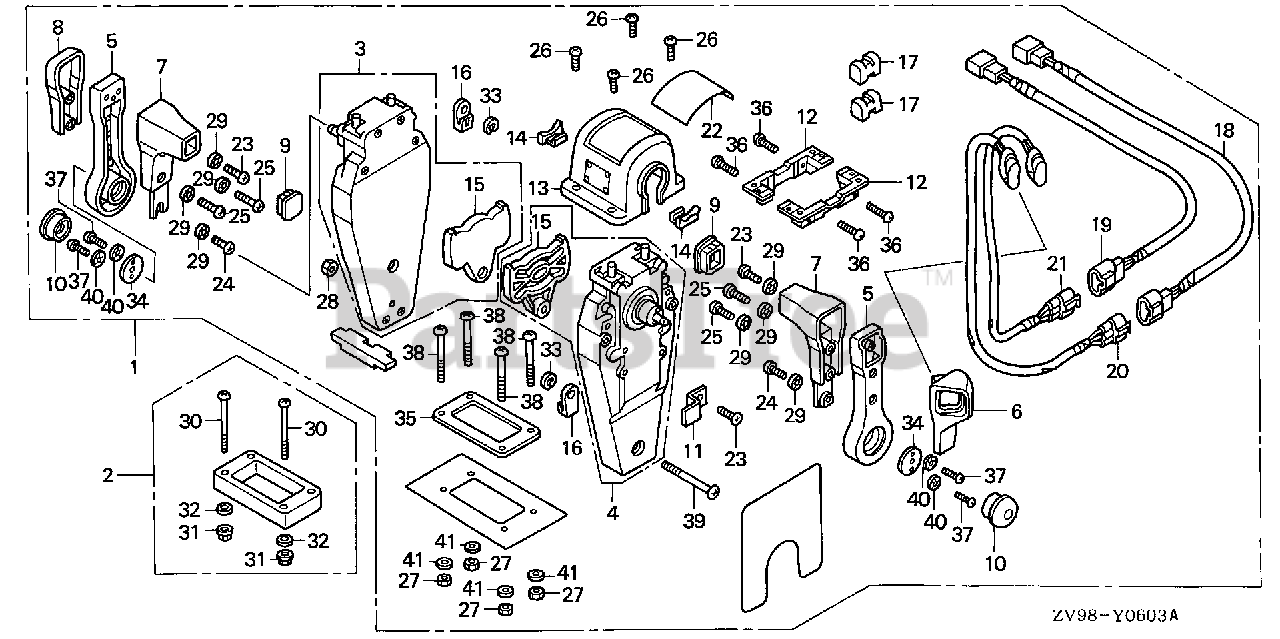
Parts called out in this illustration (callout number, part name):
1	BOX KIT, REMOTE CONTROL (TOP MOUNT DUAL)(L)
2	SPACER KIT, REMOTE CONTROL BOX (TOP MOUNT DUAL)
3	HOUSING ASSY., L. (INNER) (TOP MOUNT)
4	HOUSING ASSY., R. (INNER) (TOP MOUNT)
5	HANDLE, REMOTE CONTROL
6	COVER, R. GRIP
7	GRIP, REMOTE CONTROL HANDLE
8	COVER, DUAL GRIP
9	CAP, GRIP
10	BUTTON, THROTTLE
11	PLATE, CABLE CLAMP
12	BRACKET, REMOTE CONTROL HOUSING
13	HOUSING, DUAL REMOTE CONTROL BOX
14	HOUSING, LEAD
15	PLATE, DWELL
16	TERMINAL, CABLE
17	SPACER, CABLE CLAMP
18	SUB-HARNESS ASSY., POWER TRIM-TILT (A)
19	SUB-HARNESS ASSY., POWER TRIM-TILT (B)
20	SWITCH ASSY., POWER TRIM-TILT (A)
21	SWITCH ASSY., POWER TRIM-TILT (B)
22	MARK, REMOTE CONTROL (DUAL)
23	SCREW, PAN (5X16)
24	SCREW, PAN (5X10)
25	SCREW, PAN (5X20)
26	SCREW, PAN (4X10)
27	NUT, HEX. (5MM)
28	NUT, HEX. (5MM)
29	WASHER, LOCK (5MM)
30	SCREW, PAN (5X65)
31	NUT, FLANGE (5MM)
32	WASHER, PLAIN (5MM)
33	E-RING (6MM)
34	PLATE, HANDLE
35	GASKET, DUAL
36	SCREW, PAN (5X18)
37	SCREW, PAN (6X18)
38	SCREW, PAN (5X40)
39	SCREW, PAN (5X55)
40	WASHER, LOCK (6MM)
41	WASHER, PLAIN (5MM)
